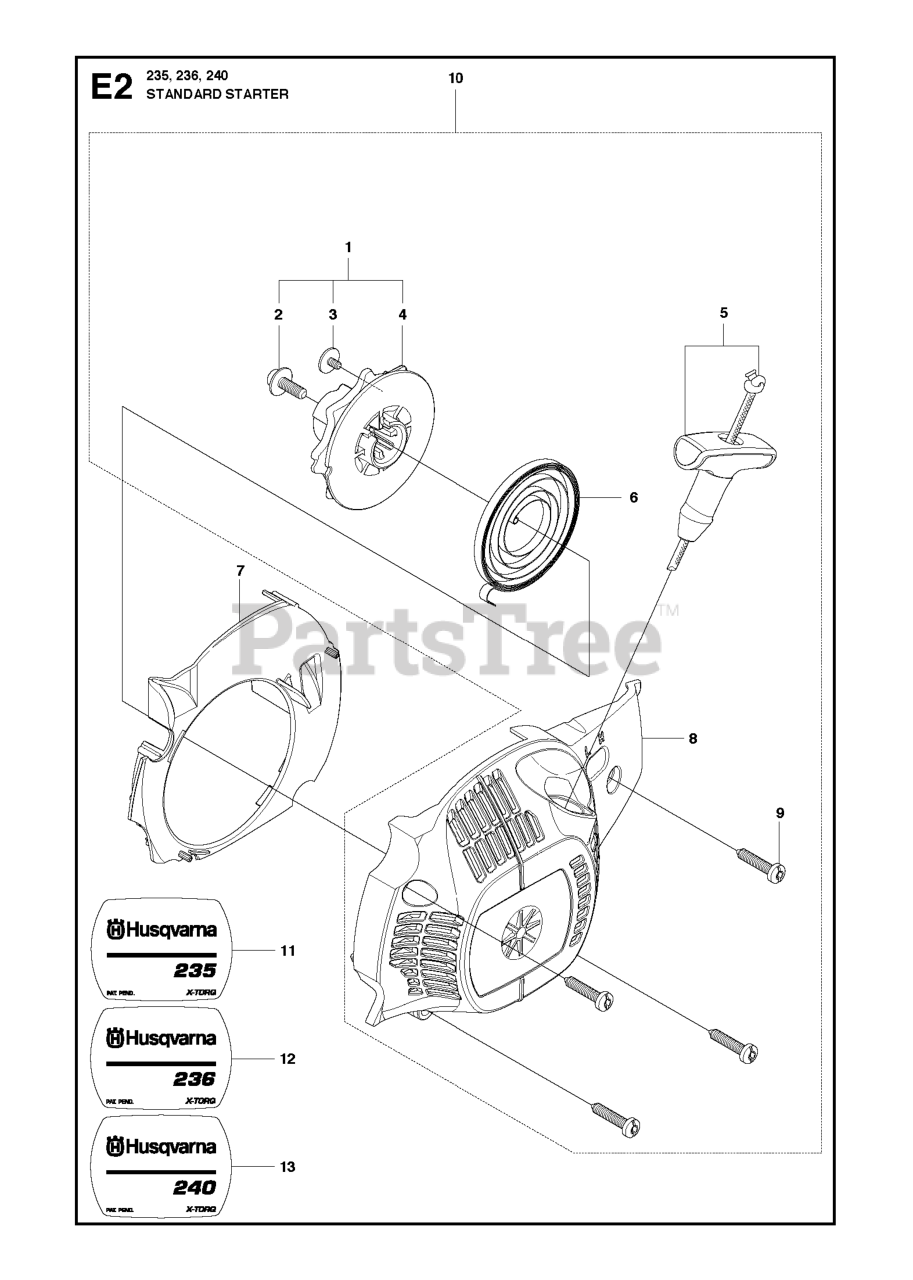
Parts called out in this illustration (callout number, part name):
1	KIT, STD STARTER
4	STARTER PULLEY
5	STARTER ROPE W/HANDLE
6	SPRING STARTER
8	FAN HOUSING
9	SCREW M5.38-14X22.225MM
10	STARTER KIT COMPLETE 235/240
